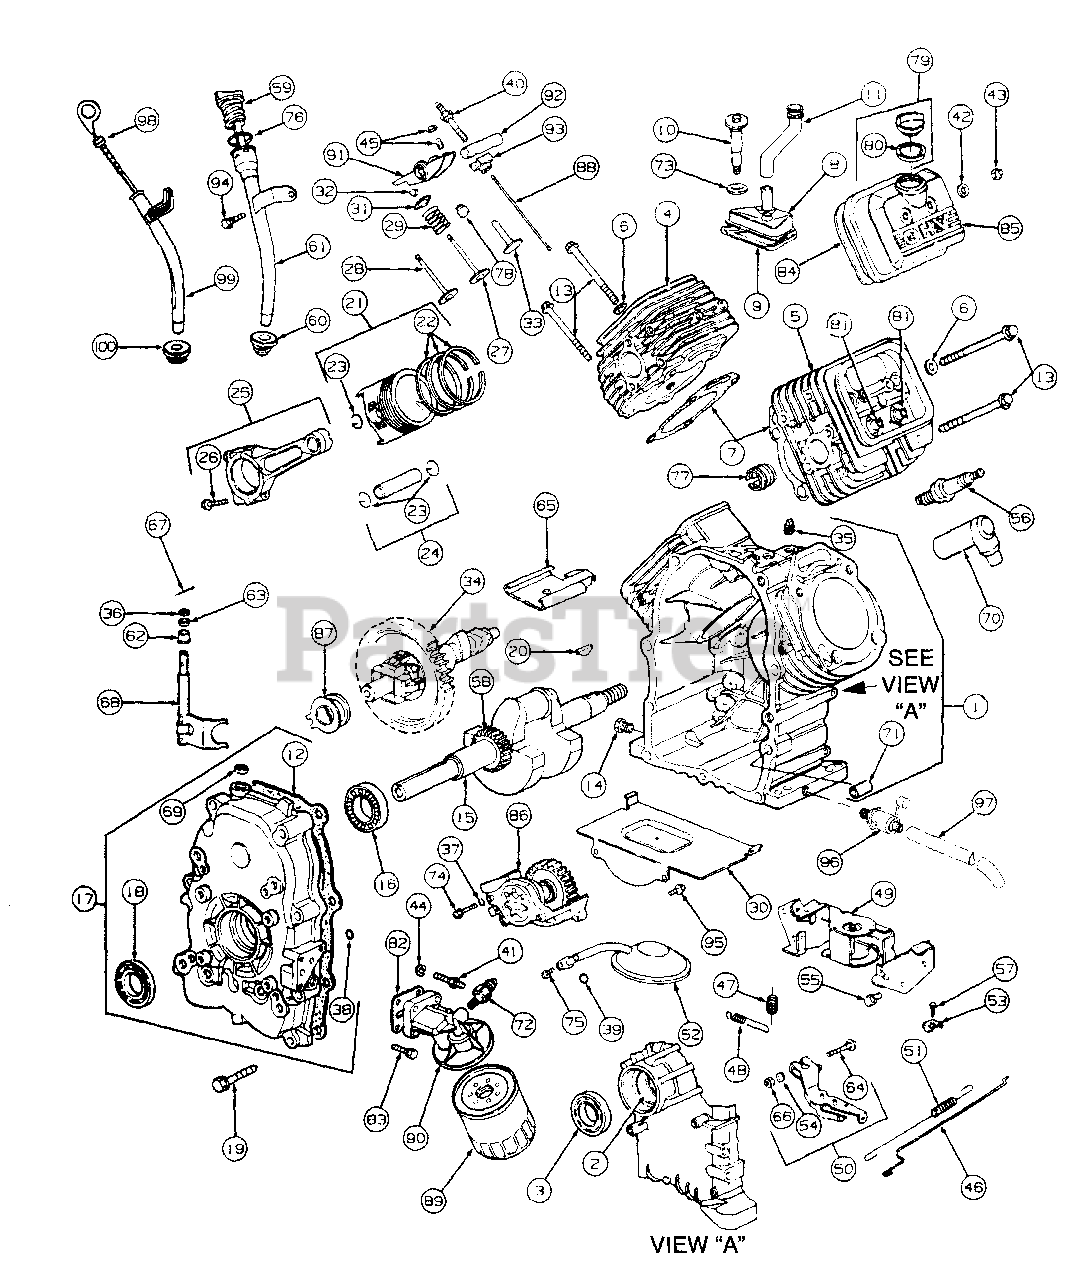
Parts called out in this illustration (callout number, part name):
1	Cylinder Assembly
3	Seal, Oil
4	Head, Cylinder (#1)
5	Head, Cylinder (#2)
7	Gasket, Cylinder Head
8	Breather Assembly
9	Gasket, Breather
10	Screw
11	Tube, Breather
12	Gasket, Cover
13	Screw
14	Plug, Oil Drain
15	Crankshaft
15	Washer, Thrust
16	Bearing, Ball
17	Cover, Crankcase
18	Seal, Oil
19	Screw, Cover
20	Key, Flywheel
21	Piston Assembly
21	Piston Assembly, .010 O.S.
21	Piston Assembly, .020 O.S.
21	Piston Assembly, .030 O.S.
22	Ring Set, Piston
22	Ring Set, Piston, .010 O.S.
22	Ring Set, Piston, .020 O.S.
22	Ring Set, Piston, .030 O.S.
23	Lock, Piston Pin
24	Pin Assembly, Piston
25	Rod Assembly
25	Rod Assembly, .020 U.S.
26	Screw, Rod
27	Valve, Exhaust
28	Valve, Intake
29	Spring, Valve
30	Plate, Windage
31	Retainer, Valve Spring
32	Retainer
33	Valve, Tappet
34	Gear, Cam
35	Plug, Pipe
36	Seal, Governor Shaft
37	O-Ring
39	O-Ring
41	Stud, Adapter
42	Washer
43	Nut, Nylock
44	Lockwasher
45	Screw, Adjustment
46	Link, Governor
47	Spring, Governor
48	Spring, Idle
49	Bracket Governor
50	Lever, Assembly
51	Spring, Governor Link
52	Screen, Pick-Up
53	Clamp, Casing
55	Screw, Sems
56	Spark Plug
57	Screw, Hex Head
58	Gear, Timing
58	Key, Timing Gear
59	Dipstick
60	Seal
61	Tube, Filler
65	Baffle, Breather
66	Nut, Hex
67	Pin, Cotter
68	Fork, Governor
69	Washer
70	Elbow, Spark Plug
72	Switch, Oil Pressure
73	Seal, Screw
74	Screw, Sems
75	Screw, Mounting
76	O-Ring
77	Liner, Exhaust Port
78	Seal, Valve Guide
79	Plug, Oil Fill
80	Seal, Fill Plug
81	Guide, Valve
82	Gasket, Adapter
83	Screw, Sems
84	Gasket, Valve Cover
85	Cover, Valve LH (Shown)
86	Oil Pump Assembly
87	Slider, Governor
88	Rod, Push
88	Rod, Push (exhaust)
89	Filter, Oil
90	Adapter, Filter
91	Arm, Rocker
94	Screw, Mounting
95	Screw, Sems
96	Drain, Oil
97	Hose, Oil Drain
98	Dipstick
99	Dipstick Tube
100	Seal
